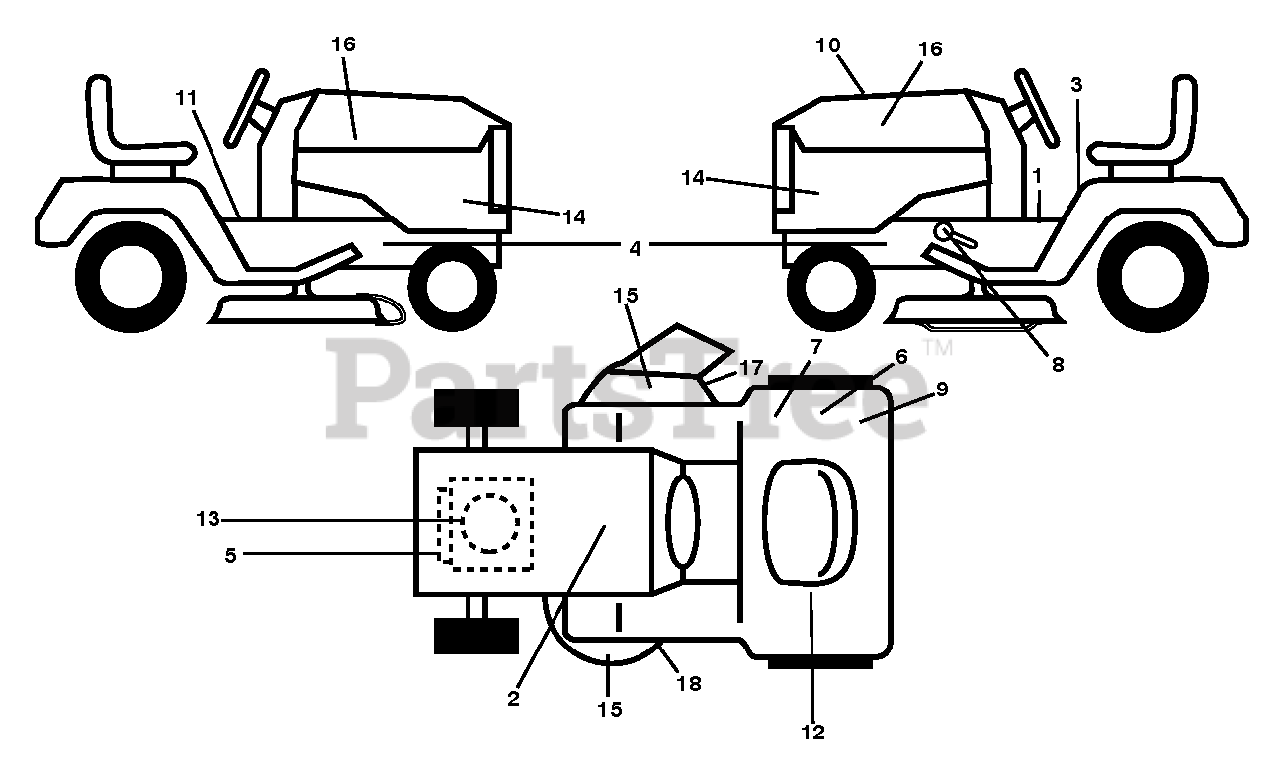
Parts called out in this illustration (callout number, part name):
1	DECAL PARK BRAKE
2	DECAL BTRY SYMBOLS
3	LABEL
5	DECAL, ENG. HP
6	DECAL 80 DBA
7	DECAL
8	DECAL.PEDAL.HUSQ.CROWN
9	DECAL
11	DECAL
12	DECAL.WARN.RESERVE.FUEL
13	DECAL
15	DECAL, NO STEP
16	RP.DECAL.BADGE.170MM.TEXTLOGO
17	DECAL, CAUTION
18	DECAL.MOWER.SCH.48/54
